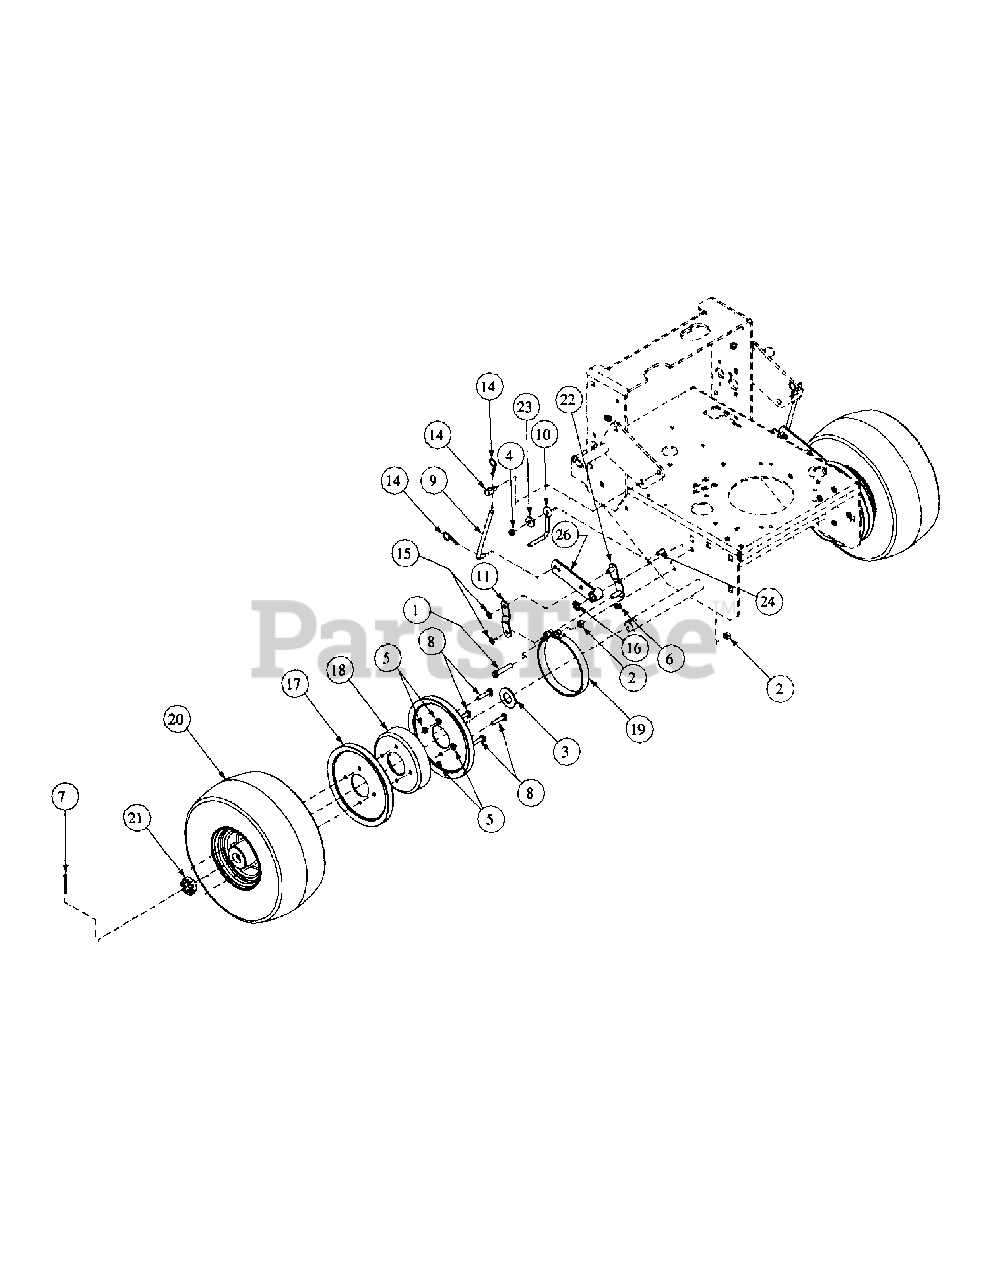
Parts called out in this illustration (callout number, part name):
1	Hex Cap Screw, 3/8-16, 2.00
2	Hex Nut, 3/8-16
3	Flat Washer, 2.000 x 1.005 x .120
4	Nut, Nylock, 5/16-18
5	Lock Washer, 5/16 Zinc
6	Grease Fitting, 1/4-28, 90°.
7	Cotter Pin, 5/32 x 1-1/2 Zinc
8	Hex Cap Screw, 5/16-18 x 1-1/2
9	Brake Rod
10	Drive Belt Guide
11	Brake, Bracket Link
12	Drive Wheel Pulley Spacer
13	Swivel Joint
14	Hair Pin, 3/8-1/2
15	Retainer, Push ON, 3/8
16	E-Ring, 5/8
17	Drive Pulley, V
18	Drum Brake
19	Band Brake
20	Wheel Assembly, 13 x 6.50-6
21	Hex Jam Nut, 1-14
22	Brake Link
23	Idler Washer
24	Carriage Bolt, 5/16-18 x 1
26	Brake Lever Weldment
